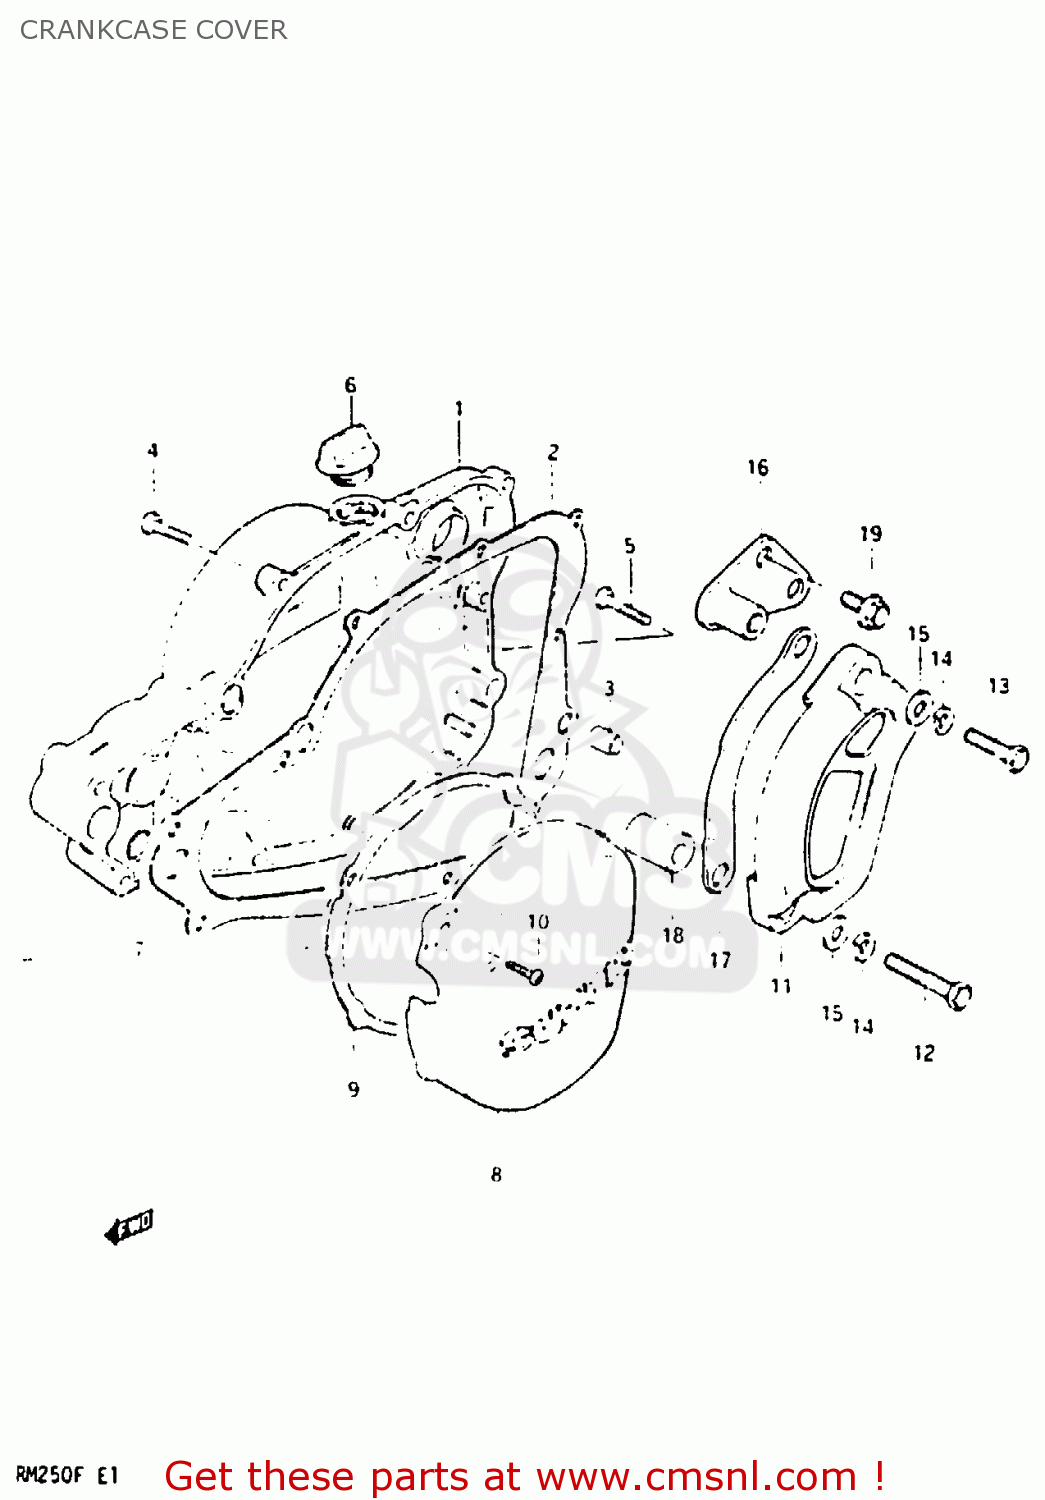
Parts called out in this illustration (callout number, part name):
1	COVER,CLUTCH
2	GASKET,CLUTCH COVER (MCA)
3	PIN
4	SCREW
5	SCREW
6	PLUG SET
7	O RING(D:2.4,ID:16.8)
8	COVER,MAGNETO
9	GASKET,MAGNETO COVER (MCA)
10	SCREW
11	COVER,SPROCKET
12	BOLT 8X55
13	BOLT
14	LOCK WASHER
15	WASHER,8.5X16X
16	BRACKET,CHAIN GUIDE PL
17	PLATE,FRONT CHAIN GUIDE
18	SPACER (8.6X16X23.5)
19	BOLT
